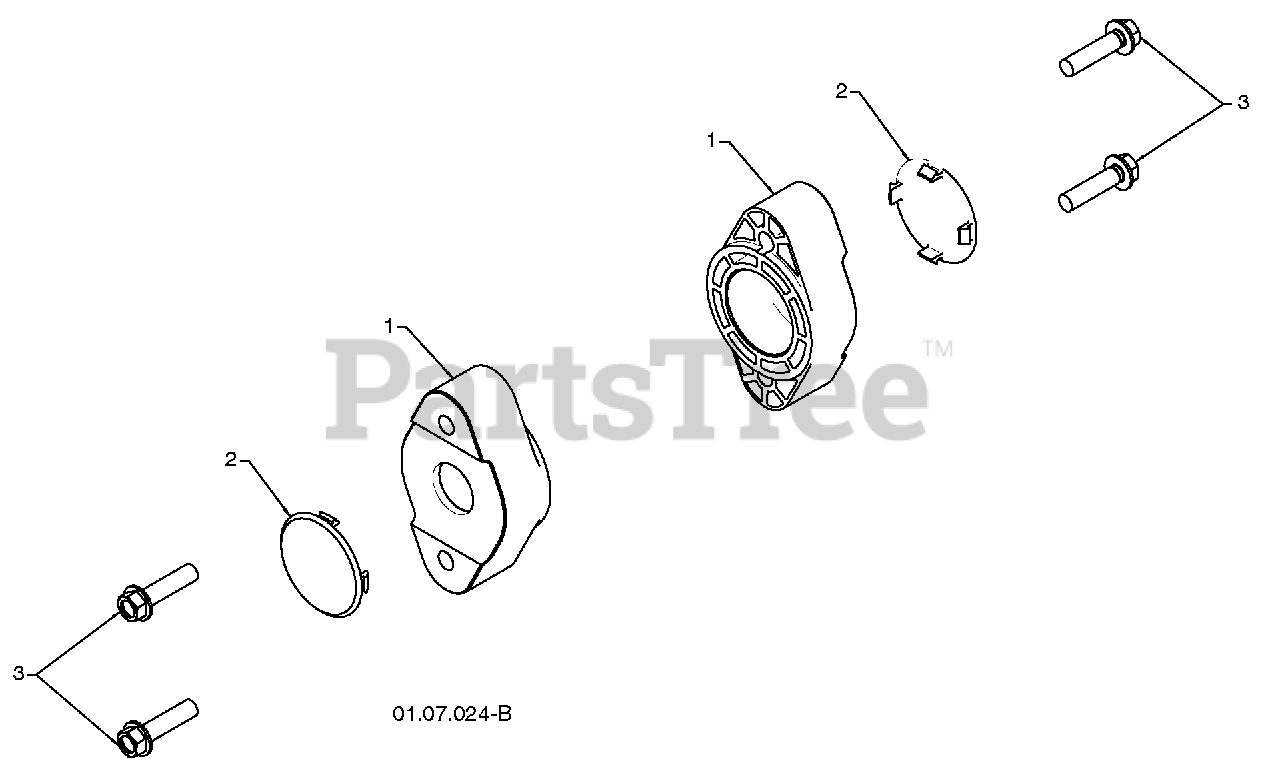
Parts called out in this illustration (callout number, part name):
1	AUGER BEARING
2	BEARING PLUG
3	SCREW 5/16-18 X 1.00
